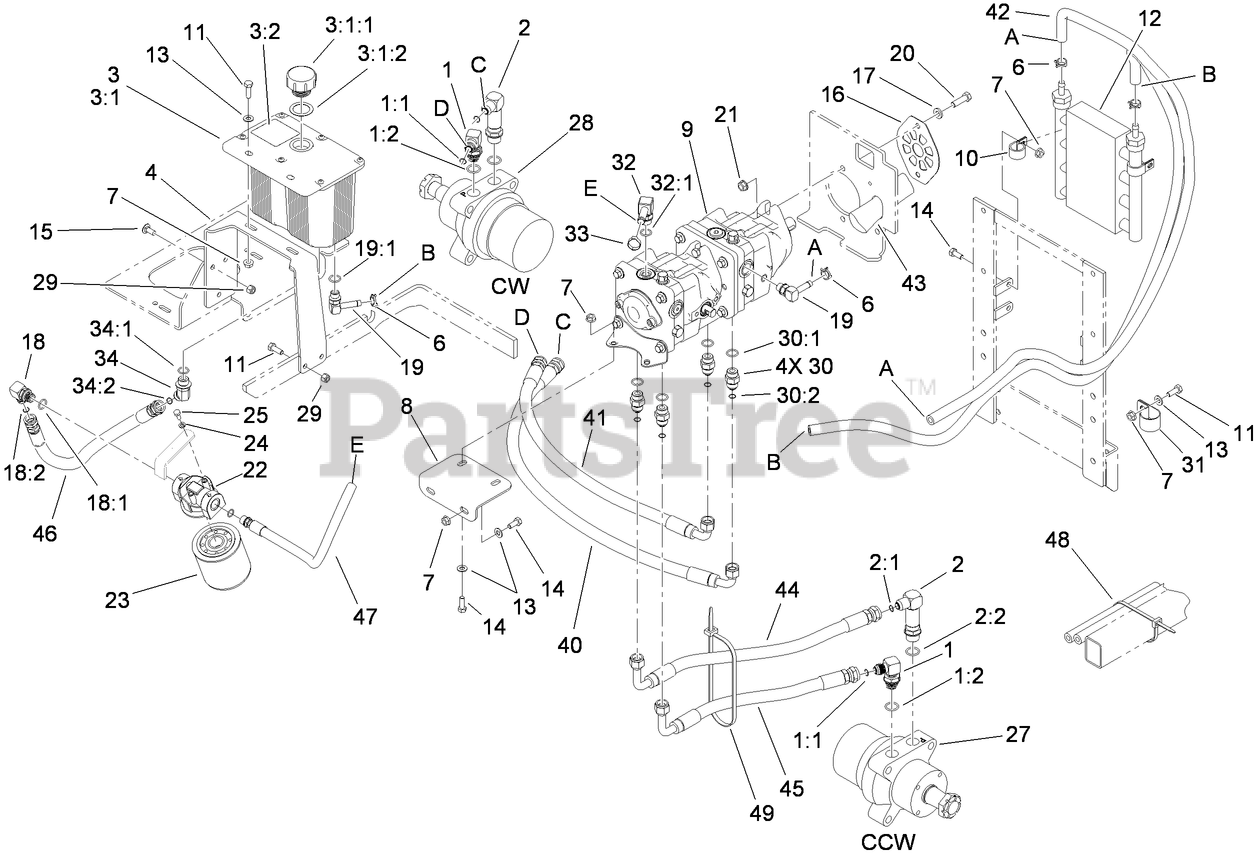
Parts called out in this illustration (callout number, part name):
1	FITTING-HYD, 90 DEG
1:1	O-Ring
1:2	O-RING
2	FITTING-ELBOW-90
2:1	O-Ring
2:2	O-RING
3	HYDRAULIC TANK ASM
3:1	TANK-HYDRAULIC
3:1:1	CAP-RESERVOIR, HYD
3:1:2	GASKET-CAP
3:2	DECAL-SURFACE, HOT (CE)
4	BRACKET-TANK, HYDRAULIC
6	CLAMP-HOSE
7	NUT-HF
8	BRACKET-PUMP, FRONT
9	TANDEM PUMP ASM
10	R-CLAMP
11	SCREW-HH
12	COOLER-OIL, HYDRO
13	WASHER-PLAIN
14	SCREW-HH
15	SCREW-CARR
16	PLATE-SHIELD, PUMP
17	WASHER-FLAT
18	FITTING-90 DEG
18:1	O-RING
18:2	O-Ring
19	FITTING-ELBOW, 90
19:1	O-RING
20	SCREW-HH
21	NUT-HHF, WHIZ
22	HEAD-FILTER
23	CARTRIDGE-FILTER, OIL
24	WASHER-LOCK
25	SCREW-HH
27	HYD MOTOR ASM (CCW)
28	HYD MOTOR ASM (CW)
29	NUT-LOCK, NI
30	FITTING-STRAIGHT
30:1	O-RING
30:2	O-Ring
31	CLAMP-R
32	FITTING-ELBOW, 90 DEG
32:1	O-RING
33	CLAMP-HOSE
34	FITTING-HYD, 45 DEG
34:1	O-RING
34:2	O-Ring
40	HYDRAULIC HOSE ASM
41	HYDRAULIC HOSE ASM
42	HOSE-HYDRAULIC
43	SLEEVE-FABRIC
44	HYDRAULIC HOSE ASM
45	HYDRAULIC HOSE ASM
46	HYDRAULIC HOSE ASM
47	HYDRAULIC HOSE ASM
48	TIE-PLASTIC
49	CABLE TIE-PLASTIC
